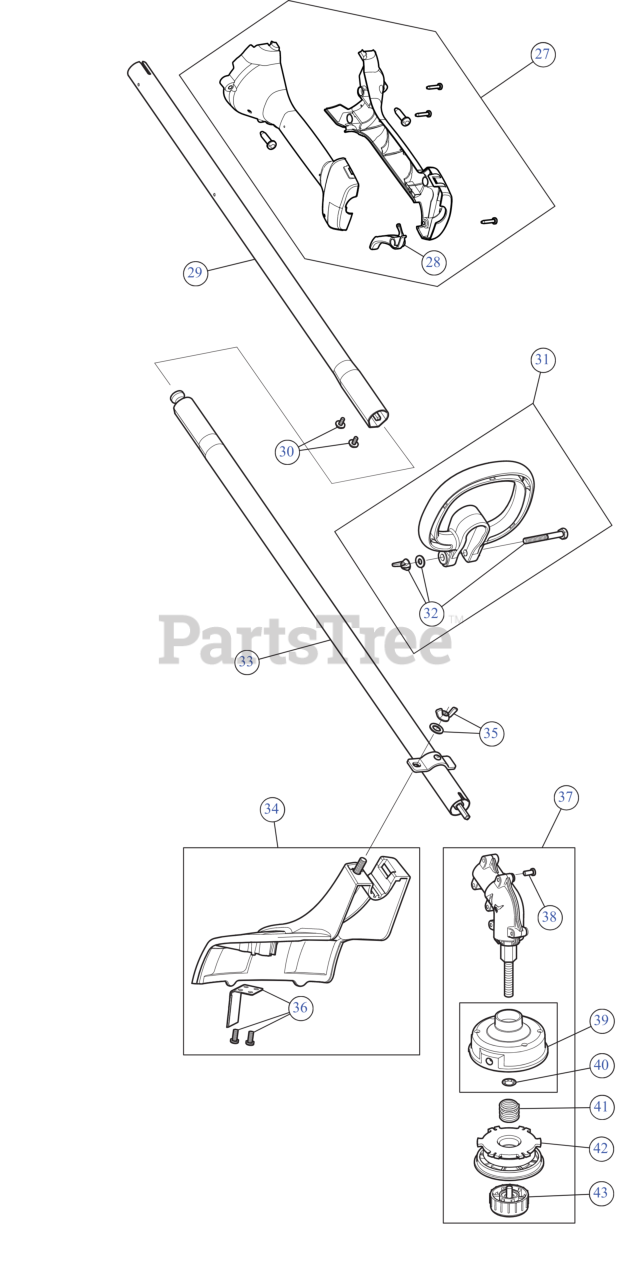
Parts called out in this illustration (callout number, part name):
27	THROTTLE GRIP ASSEMBLY
28	THROTTLE TRIGGER
29	UPPER BOOM ASSEMBLY
30	SCREW 8-32X3/8
31	HANDLE
32	HANDLE HWD
33	LOWER BOOM ASSEMBLY
34	GUARD & BLADE ASSEMBLY
35	BLADE GUARD MOUNTING HARDWARE
36	BLADE ASSEMBLY W/HDW
37	GEARBOX ASSEMBLY
38	SCREW 8-32X.437
39	REEL:OTR W/RET
40	RETAINER .625 OD 2
41	SPRING-SPOOL
42	REEL-INNER SPOOL
43	BUMP HEAD KNOB ASSEMBLY
